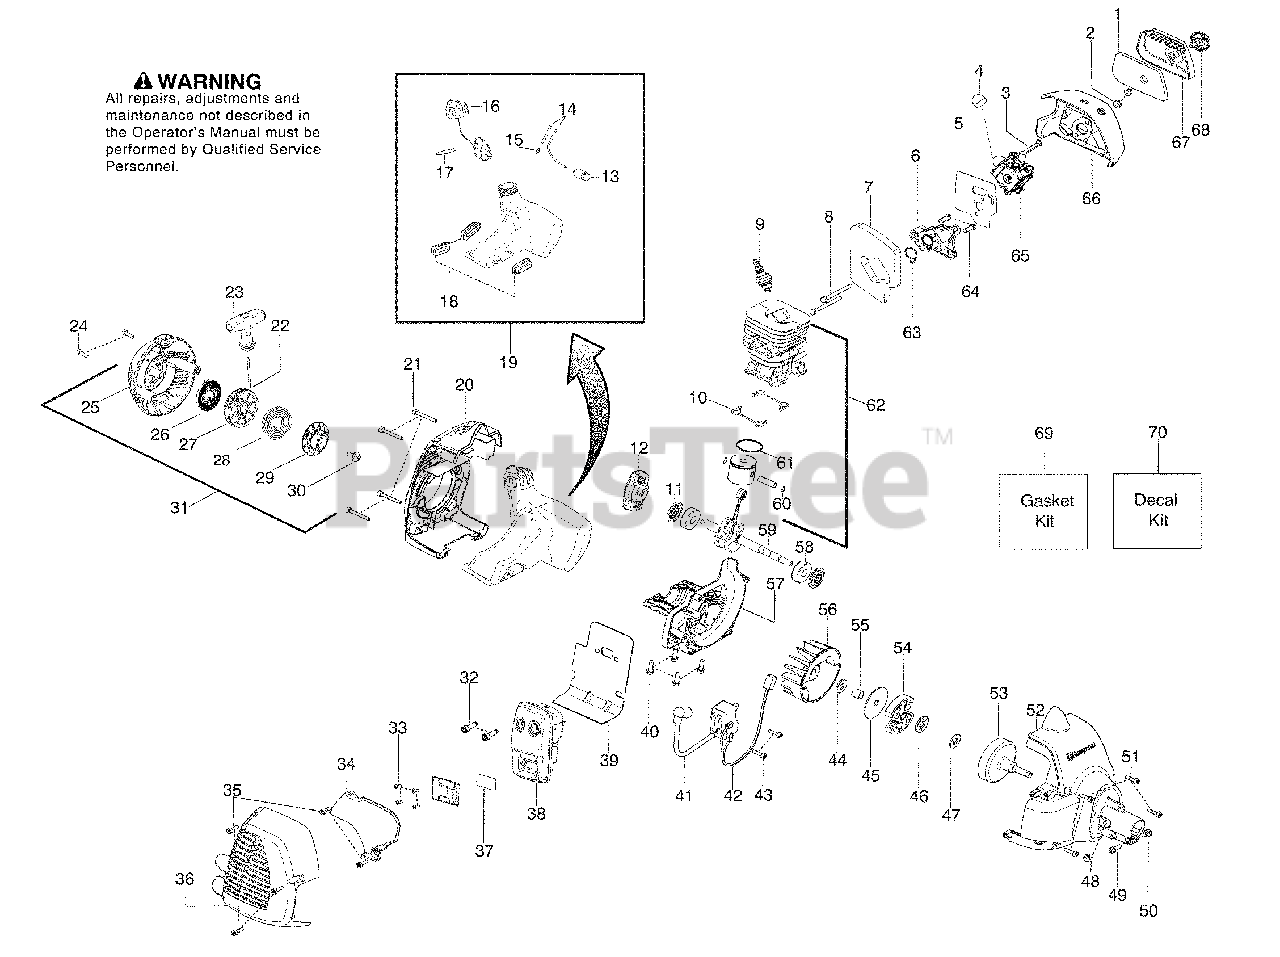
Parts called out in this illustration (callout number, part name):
2	Nut - Carb. Screw
3	Lever - Choke
4	Bulb - Purge
5	Kit - Carb. Gasket
6	Adaptor - Carb.
7	Foam – Gasket
9	Plug - Spark (RCJ-8Y)
10	Seal – Cylinder
11	Seal – Crankshaft
12	Assy - Starter Pawl
13	Assy - Fuel Filter
14	Kit - Fuel Line
15	Fitting - Fuel line
16	Assy - Cap w/ret
17	O-ring - Fuel Cap
18	Isolator - Fuel Tank
19	Kit - Fuel Tank Assy.
20	Shroud - Rear
22	Kit - Rope
23	Handle - Starter
25	Hsg. - Starter w/eyelet
26	Kit - Spring
27	Kit - Starter Pulley
28	Spring - Driver
29	Pulley - Driver
31	Assy - Starter Hsg.
32	Bolt - Muffler
33	Screw
34	Shield - Heat
36	Guard - Muffler
37	Kit – Spark
38	Kit - Muffler
39	Gasket - Paper Met.
42	Assy - Leadwire
45	Washer - Clutch
46	Bearing - Thrust
47	Washer - Thrust
52	Assy - Fan Housing
53	Assy - Clutch Drum
54	Assy - Clutch
57	Crankcase - Cast
59	Assy - Crankshaft
60	Retainer - Piston Pin
61	Ring - Piston
62	Kit – Piston/Cyl.
63	Seal – adaptor
65	Kit – Carb.
66	Airbox
67	Cover - Air Box
68	Assy - Knob
69	Kit - Gasket
70	Kit - Decal
